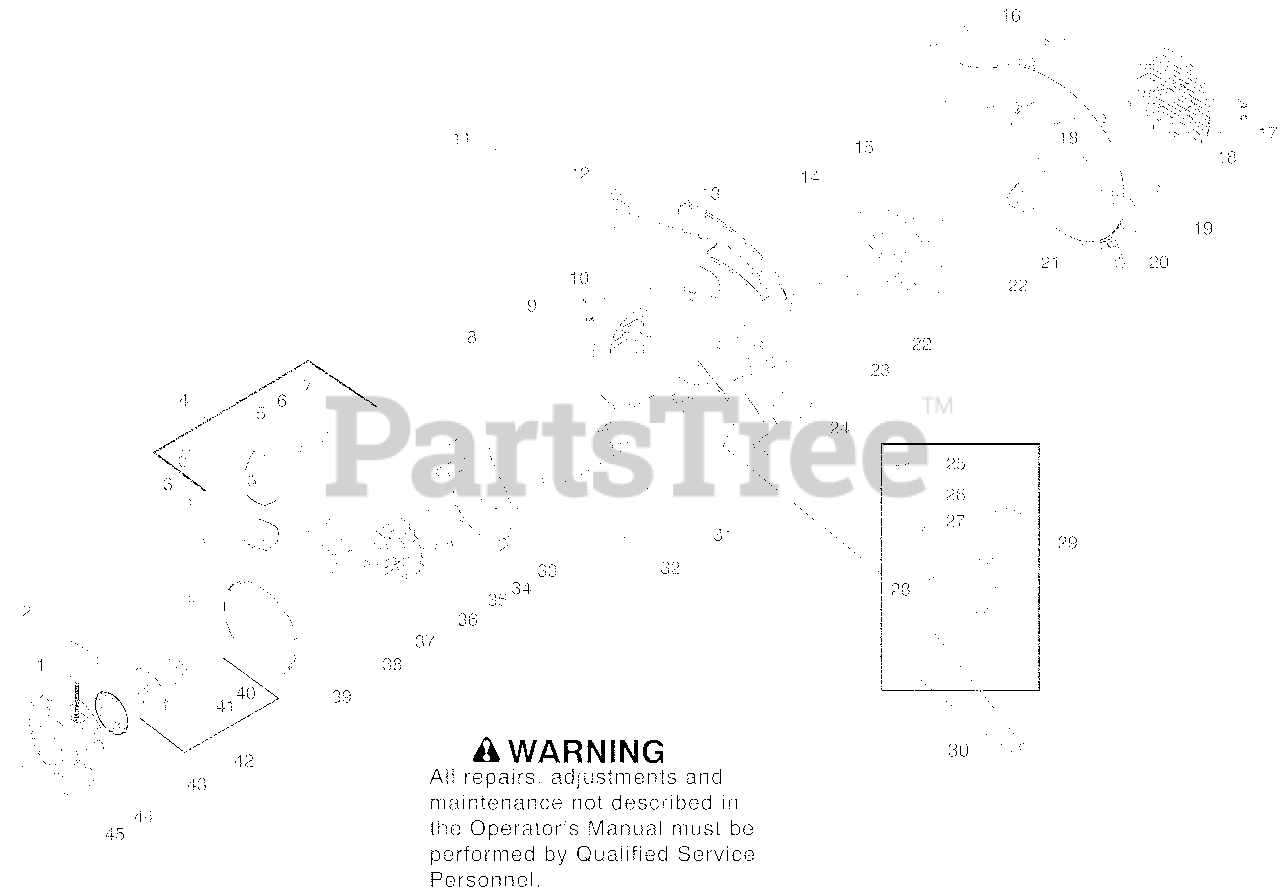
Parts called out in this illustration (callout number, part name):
1	Kit - Rope
2	Handle - Starter
4	Kit - Cruise Control
5	Washer - Wave
6	Ratchet - Cruise Control
8	Foot - Front Impact
9	Assy. - Muffler Guard
10	Assy - Blower Knob
11	Wire - Linkage
12	Trigger - Throttle
13	Wire - Handle Ground
14	Impeller
16	Nut - Blower Tube Knob
17	Spring - Vac Door
18	Cover - Vac Door
20	Assy - Outer scroll
21	Nut - Impeller
22	Washer - Impeller
24	Scroll - Inner
25	Bulb - Purge
26	Kit - Fuel line grommet
27	Assy - Fuel cap with retainer
28	Assy - Fuel pickup
29	Assy - Fuel tank
30	Screw - Fuel tank
31	Foot - Rear Impact
33	Scroll - Flywheel
35	Screw
36	Assy - Flywheel
38	Nut - Flywheel
39	Cover - Motor housing
42	Kit – Starter
43	Spring - Starter
44	Housing - Starter Cover
45	Screw
